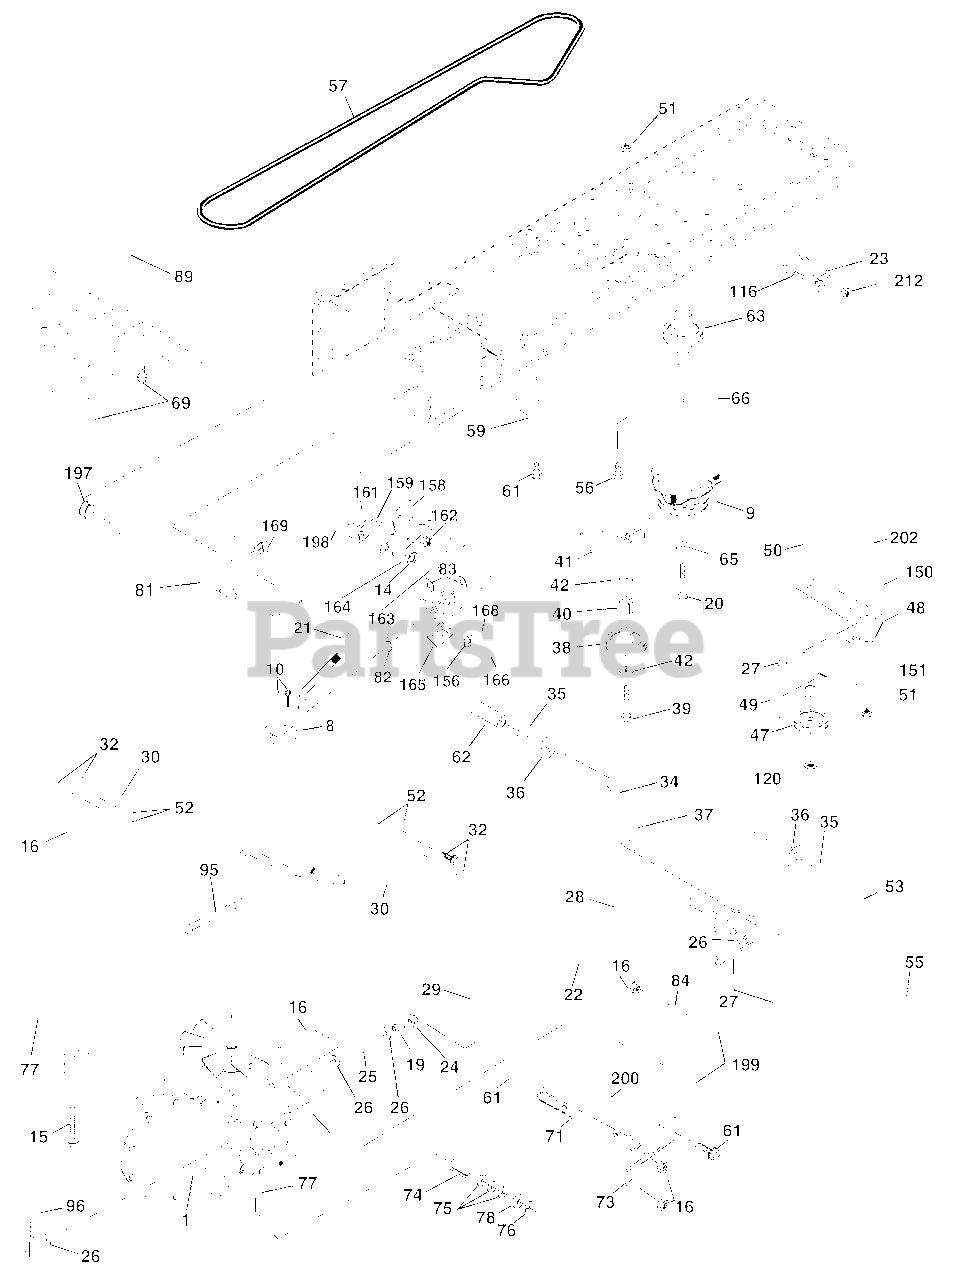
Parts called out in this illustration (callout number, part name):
8	Rod Shift Fender
9	Clutch Electric
10	Pin Cotter 1/8 x 1 CAD
14	Washer Lock Hvy Helical
15	Bolt Hex Flghd 5/16-18 Gr. 5
16	Nut Lock Hex W/Ins. 5/16-18 Unc
19	Nut Lock Hex W/Wsh 3/8-16 Unc
20	Bolt, Hex 7/16-20 x 4-1/4
21	Knob Deluxe
22	Rod, Brake Hydro
23	Bracket Asm. Anti-Rot EVX
24	Locknut
25	Spring, Brake Rod
26	Washer
27	Pin Cotter 1/8 x 3/4 CAD.
28	Rod, Parking Brake
29	Cap, Parking Brake
30	Bracket, Transaxle
32	Bolt Hex Hd 5/16-18 Unc x 3/4
33	Bolt Carriage 5/16-18 UNC x 3/4
34	Shaft, Foot Pedal
35	Bearing, Nylon
36	Washer
37	Pin, Roll
38	Pulley, Idler, Flat
39	Bolt
40	Spacer Split
41	Keeper, Belt Idler Fool-Proof
42	Washer 13/32 x 13/16 x 12 Gauge
47	Pulley, Idler, V-Groove
48	Bellcrank Clutch Grnd Drv Stl
49	Retainer, Belt
50	Bolt
51	Nut
52	Nut Crown Lock 5/16-18
53	Link, Clutch
55	Spring, Return, Clutch
56	Bolt
57	V-Belt, Ground Drive
59	Keeper, Center Span
61	Screw 3/8-16 x 3/4
62	Cover, Pedal
63	Pulley, Engine
65	Washer
66	Keeper Belt Engine Hydro
69	Screw Hexwsh Hi-Lo 1/4-1/2 UNC
71	Strap Torque Lh Hydro
73	Strap Torque Rh Hydro
74	Spacer, Axle
75	Washer 25/32 x 1-1/4 x 16 Ga.
76	E-Ring
77	Key, Square
78	Washer 25/32 x 1-5/8 x 16 Ga.
81	Shaft Asm. Cross Hydro
82	Spring Torsion T/A
83	Washer 17/32 x 3/4 x 16 Ga.
84	Link Transaxle
89	Console, Shift
95	Control Asm. Bypass Hydro
96	Retainer Spring 1" Zinc/Cad
144	Washer 11/32 x 5/8 x 16 Ga.
150	Bushing Bellcrank Grd Drive
151	Washer 13/32 x 2 x 10 Ga.
156	Washer Srrted 5/16ID x 1.125
158	Bracket Shift Mount
159	Hub Tapered Flange Shift Lt
161	Bolt Rdhd Sqnk 1/4-20 x 3/4 Gr. 5
162	Nut Crownlock 1/4-20 Unc
163	Bolt Hex Fin 1/4-20 Unc x 1 Gr. 5
164	Washer 5/8 x .281 x 10 Ga
165	Bracket Pivot Lever
166	Screw 5/16-18 x 5/8
168	Bolt Shoulder 5/16-18 x .561
169	Plate Fastening Lt\
197	Nyliner Snap-In 5/8" ID
198	Washer Nyliner 7/8 ID x .105
199	Bolt Shoulder 5/16-18 Unc
200	Bolt Rdhd Sqnk 5/16-18 UNC x 1
202	Bolt Carr Sh 3/8-16 x 1-1/2 Gr.5
